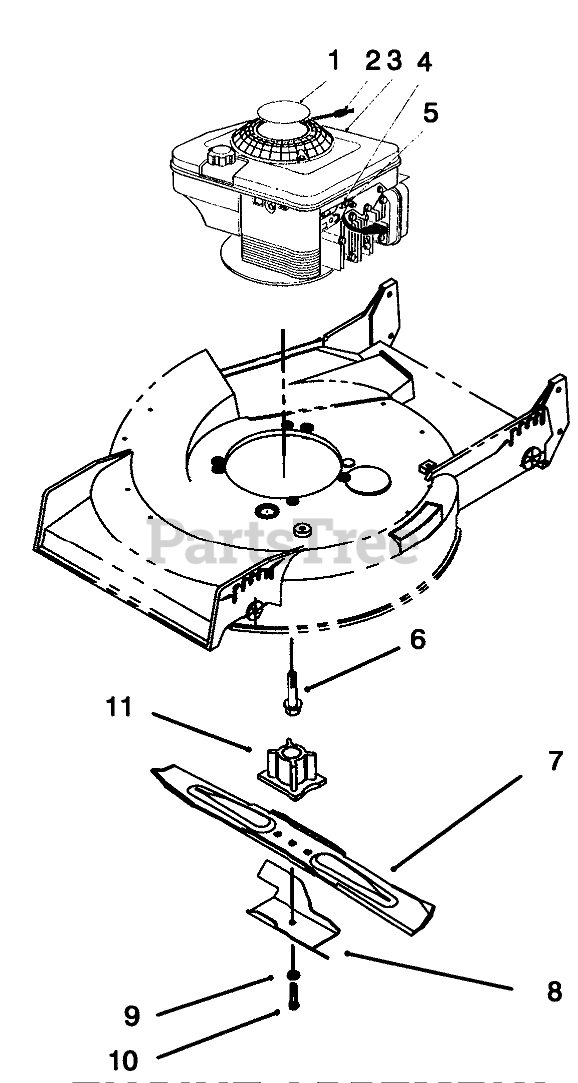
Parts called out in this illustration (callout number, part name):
1	DECAL-ENG F/W ENGINE
2	STOP-ROPE
4	CLAMP-CASING
5	CLAMP SCREW F/W ENGINE
6	SCREW-HWH
7	Blade
8	Accelerator
9	WASHER-LOCK
10	SCREW-BLADE
11	BLADE RETAINER
